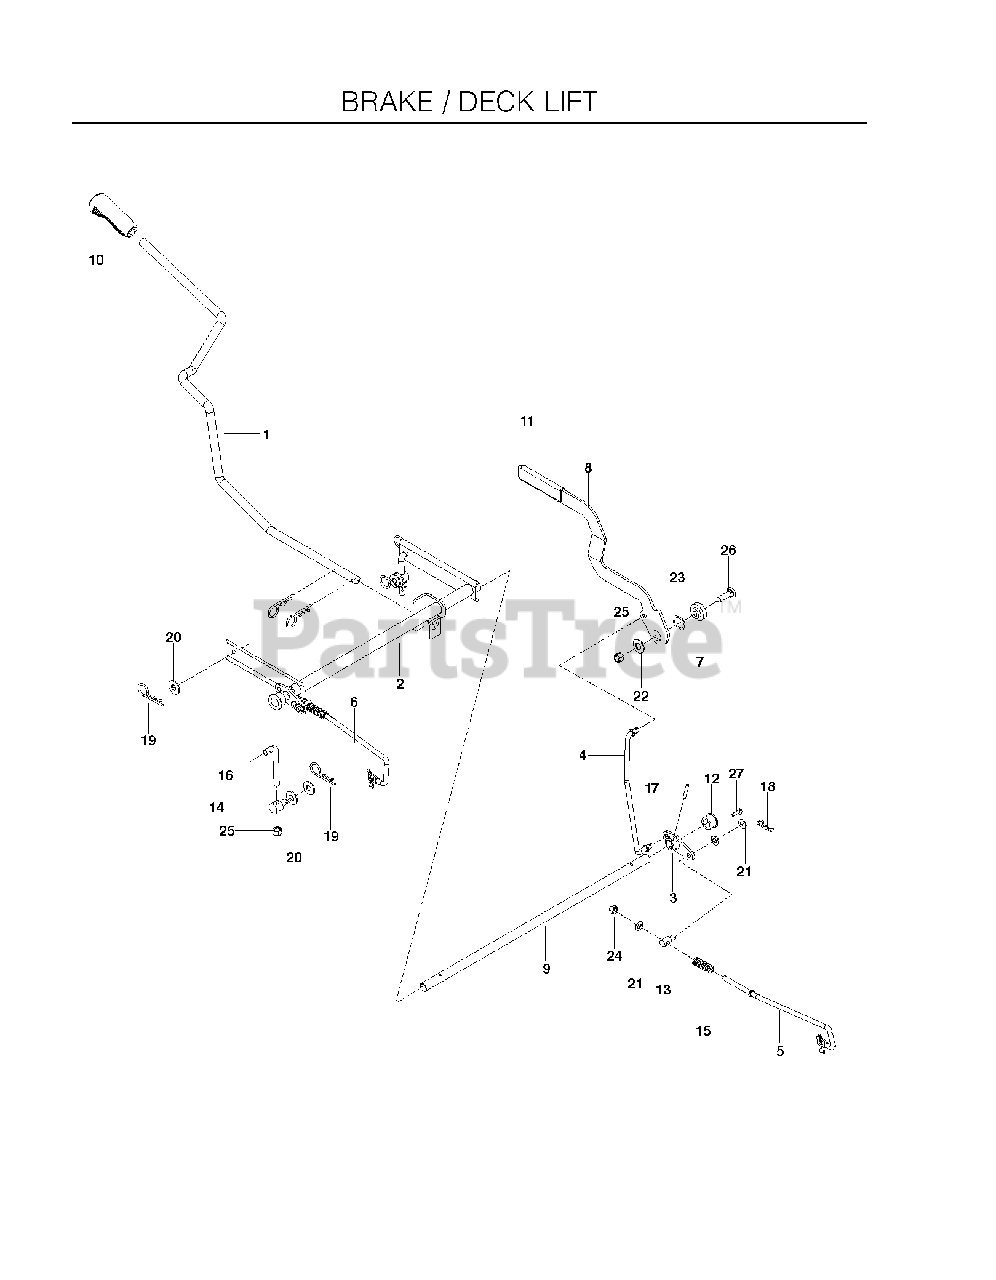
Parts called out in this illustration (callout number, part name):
1	ARM, LIFT HANDLE, BLK
2	SHAFT, LIFT WLDMT, BLACK
3	BELLCRANK, BRAKE
4	LINKAGE, BRAKE, UPPER
5	LINKAGE, EZT BRAKE RT
6	LINKAGE, EZT BRAKE LT
7	BRAKE ARM PIVOT
8	HANDLE, BRAKE, BLK
9	ROD, BRAKE
10	GRIP.LEVER.5625.ID
11	GRIP BRAKE HANDLE
12	PLASTIC BUSHING
13	BRAKE SWIVEL
16	L ROD 3-1/8"
17	ROLL PIN 3/16 X 1
18	HAIRPIN #2
19	HAIRPIN #4
20	WASHER 3/8 FLAT
21	FLAT WASHER 5/16 SAE
22	WASHER, 7/16 DISC SPRING
23	WASHER, .825 X 1.087, WAVE
24	NUT 5/16 NYLOC
25	NUT 3/8-16 NYLOC
26	RHSNB 3/8-16 X 1-1/4
27	SCREW #10 X 1/2 SELF TAPPING
